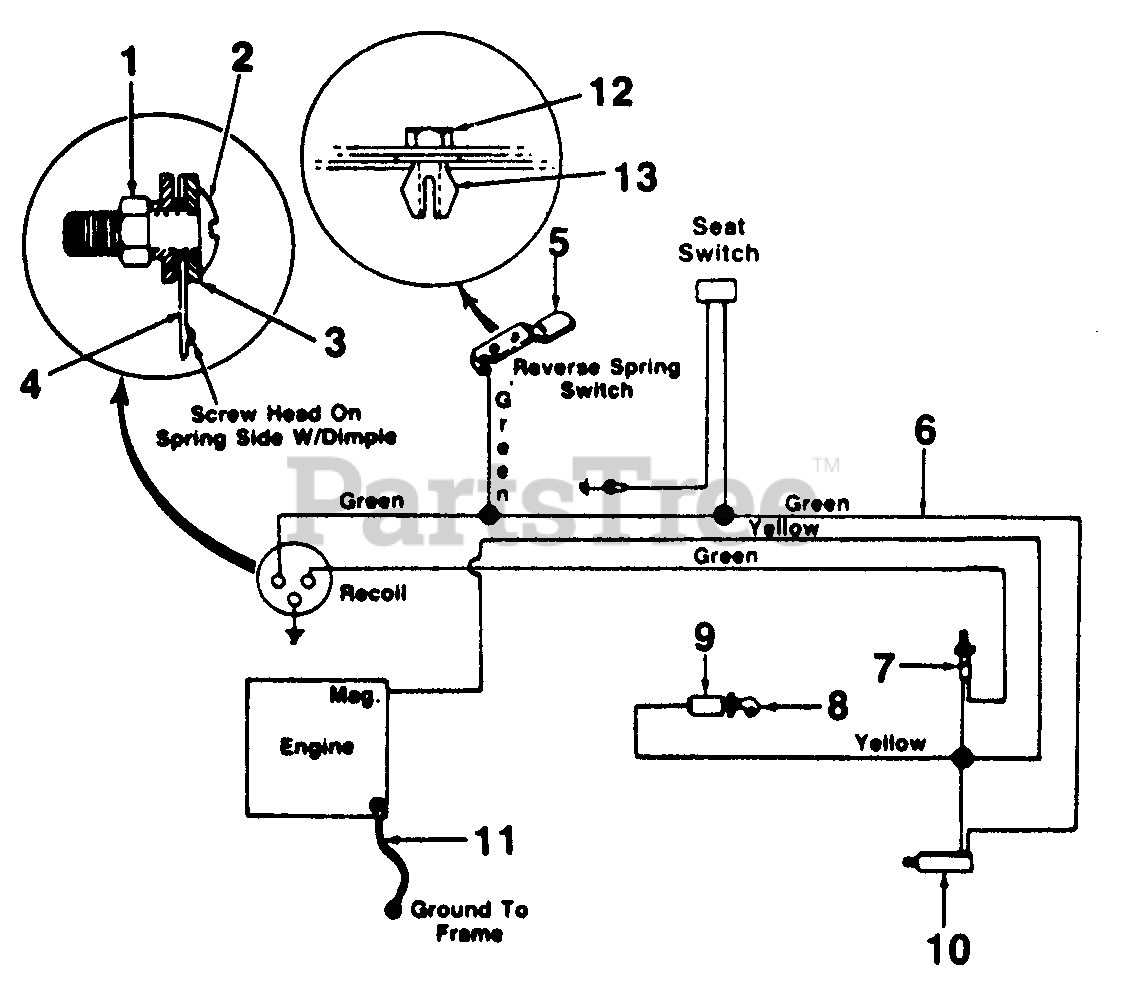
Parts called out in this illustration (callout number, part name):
1	Hex Nut #10-24 Thd.
2	Truss Mach. Scr. #10-24 x .62" Lg.
3	Fiber Washer
4	Switch Spring-Recoil
5	Spring Switch-Reverse
6	Wire Harness
7	Safety Switch-Red N.C.- Clutch
8	Ignition Key
9	Ignition Switch
10	Safety Switch-P.T.O.
11	Ground Wire
12	C-Sunk S-Tap Scr. #8 x .5" Lg.
13	Push-In Nut #10
